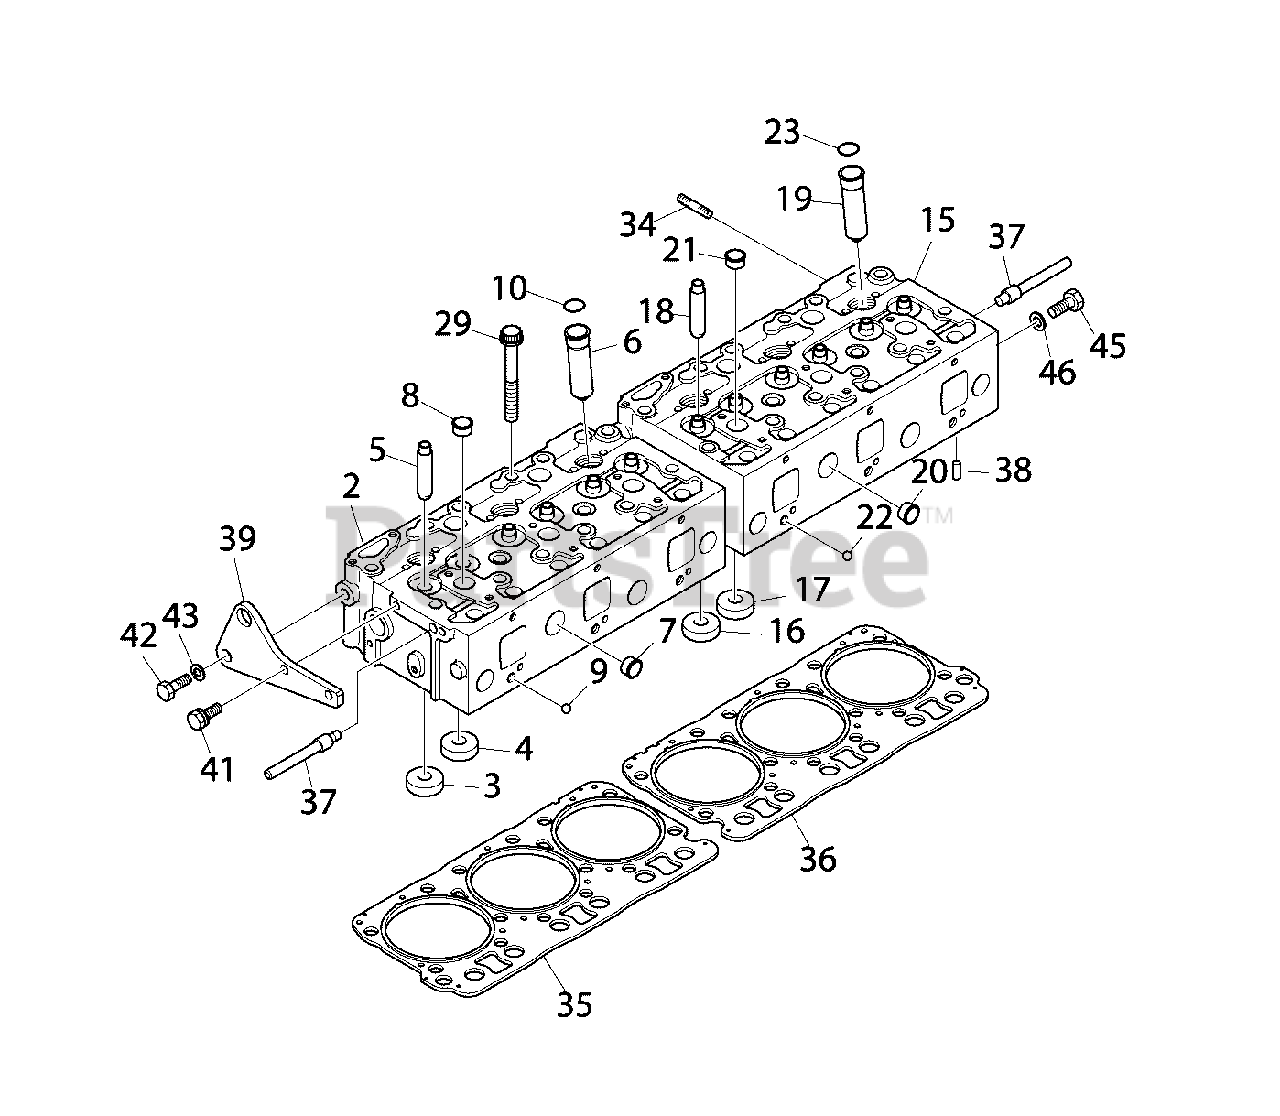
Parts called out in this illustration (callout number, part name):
1	* HEAD, CYLINDER (FRONT)
3	* SEAT, VALVE
4	* SEAT, INT VALVE
5	* GUIDE, VALVE
6	* TUBE, INJ/NOZZLE
7	* PLUG, CORE
8	* PLUG, CORE
9	* STEEL, BALL
10	* O-RING
14	* HEAD, CYLINDER (REAR)
16	* SEAT, VALVE
17	* SEAT, INT VALVE
18	* GUIDE, VALVE
19	* TUBE, INJ/NOZZLE
20	* PLUG, CORE
21	* PLUG, CORE
22	* STEEL, BALL
23	* O-RING
29	* BOLT
34	* BOLT, HEX
35	GASKET, CYLINDER HEAD
36	GASKET, CYLINDER HEAD
37	* PLUG, HEAD
38	* PIN, DOWELL
39	* BRACKER, HANGER
41	* BOLT
42	* BOLT, HEX
43	* WASHER, SPRING
45	* BOLT, HEX
46	* WASHER, SPRING
